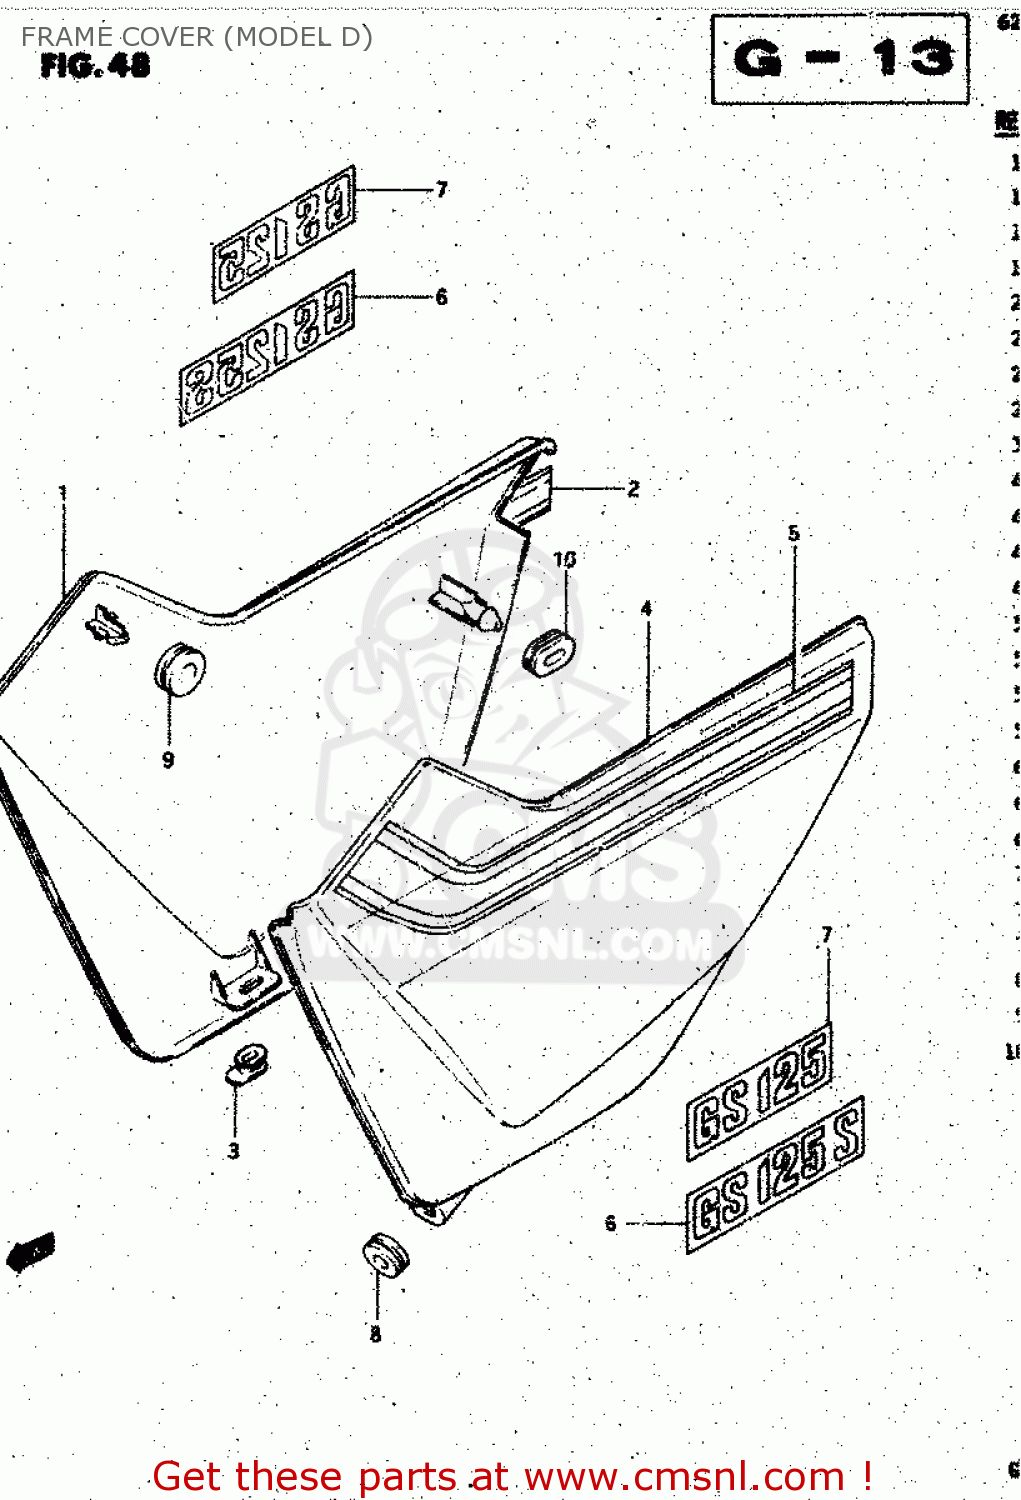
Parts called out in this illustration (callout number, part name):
1	COVER, FRAME RH (RED)
2	TAPE SET, FRAME COVER RH
3	CUSHION
4	COVER, FRAME LH (RED)
5	TAPE SET, FRAME COVER LH
6	EMBLEM
7	EMBLEM (GOLU)
8	CUSHION
9	CUSHION
10	CUSHION
